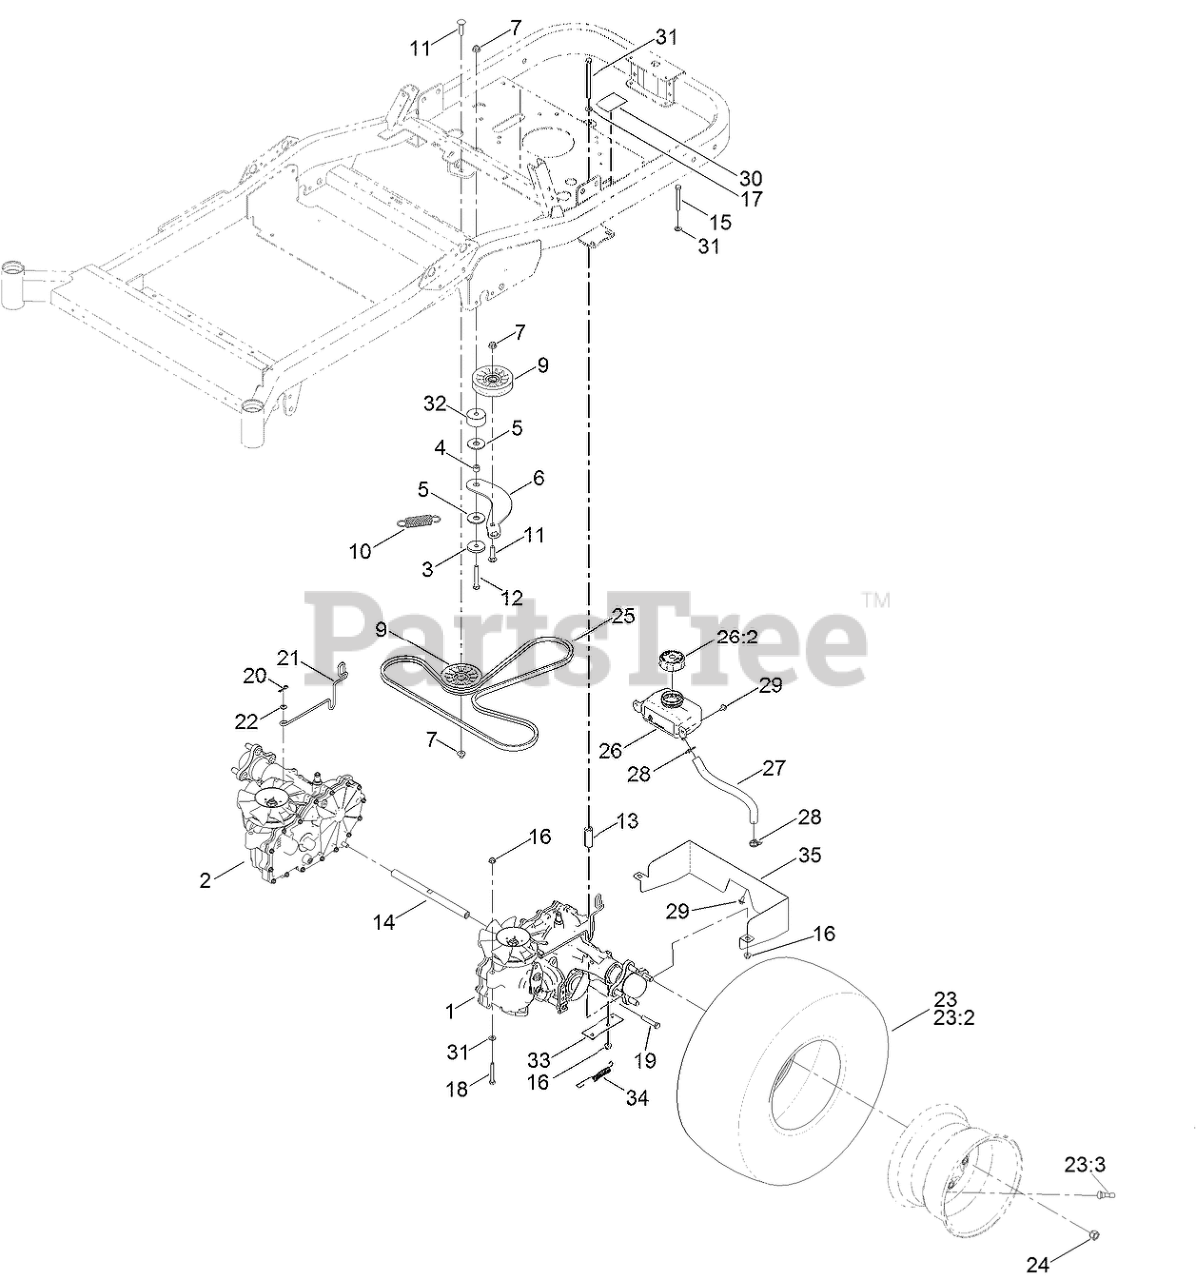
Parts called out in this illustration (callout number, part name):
1	LH HYDRO TRANSMISSION ASM
2	RH HYDRO TRANSMISSION ASM
3	WASHER-PLAIN
4	SPACER
5	WASHER-FRICTION, COMPOSITE
6	ARM-IDLER
7	NUT-HF, NI
9	PULLEY-IDLER, FLAT
10	SPRING-EXTENSION
11	SCREW-CARR
12	SCREW-HH
13	SPACER-HYDRO
14	SHAFT-CROSS, HYDRO
15	SCREW-HH
16	NUT-HF, NI
17	SCREW-HH
18	SCREW-HH
19	SCREW-HH
20	PIN-COTTER
21	ROD-BYPASS
22	WASHER
23	TIRE AND WHEEL ASM
23:3	STEM-VALVE
24	NUT-LUG
25	V-BELT
26	HYD RESERVIOR ASM
26:2	CAP-RESERVOIR, HYD
27	HOSE-OVERFLOW
28	CLAMP-HOSE
29	SCREW-HHFTF
30	DECAL-BYPASS
31	WASHER-PLAIN
32	SPACER
33	PLATE-SPRING
34	SPRING-EXTENSION
35	Guard, Rear
